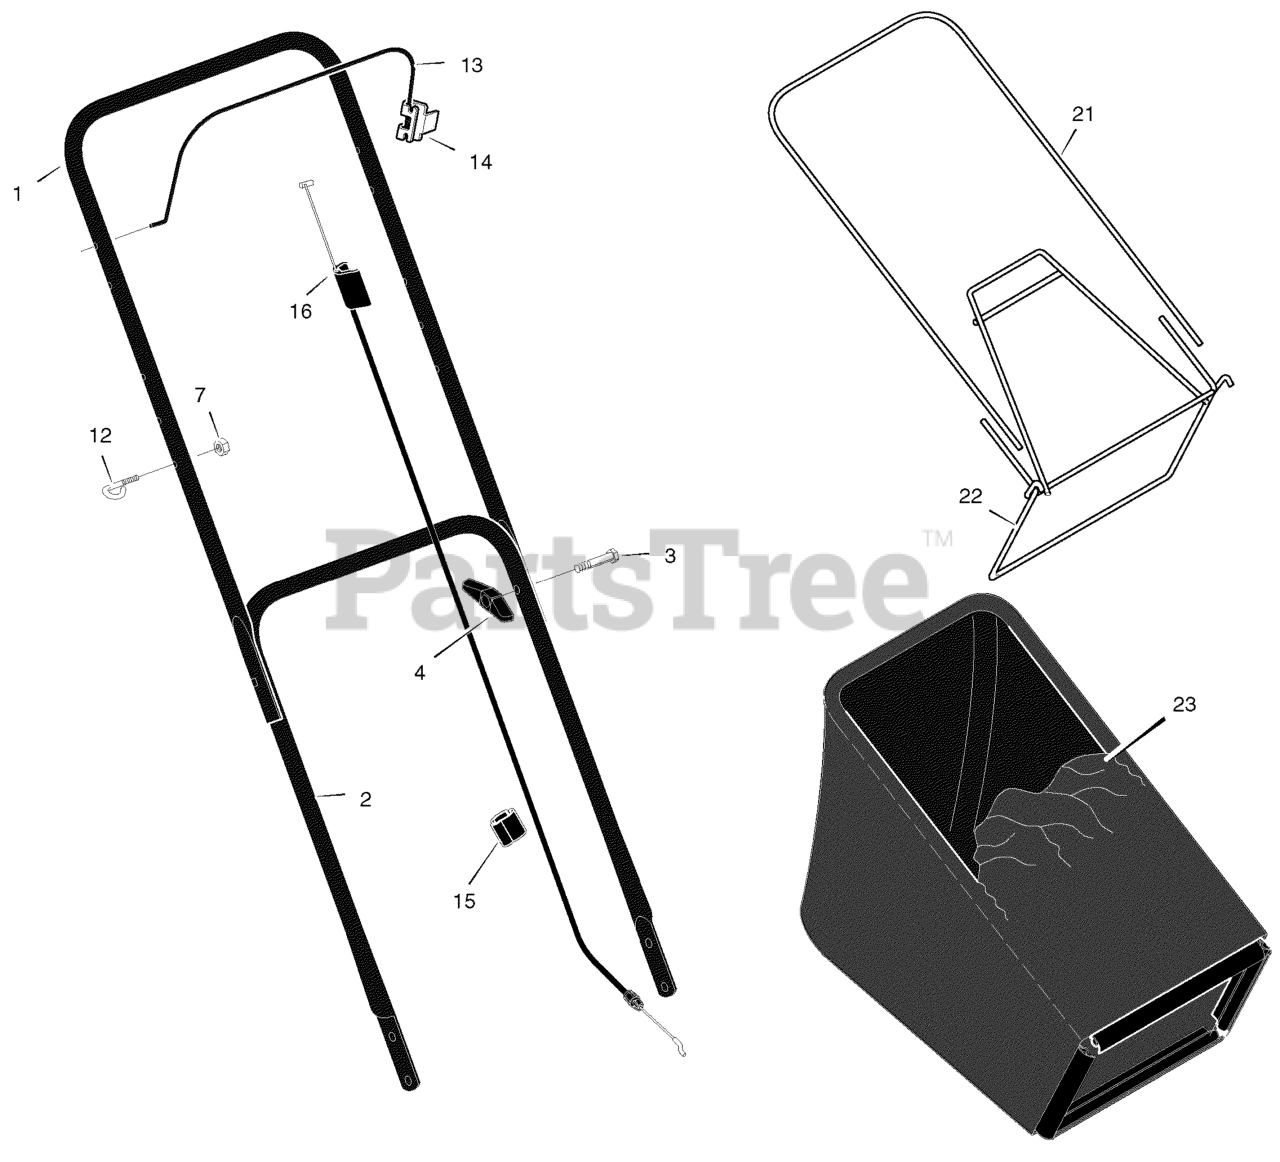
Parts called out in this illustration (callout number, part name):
1	Handle, Upper, Black
2	Handle, Lower, Black
4	Knob, Plastic
7	Locknut
12	Guide, Rope
13	Engine Stop Lever
14	Bracket, Stop Lever
15	Fastener, Cable
16	Engine Stop Cable
21	Frame, Top
22	Frame Assembly
23	Bag, Cloth
